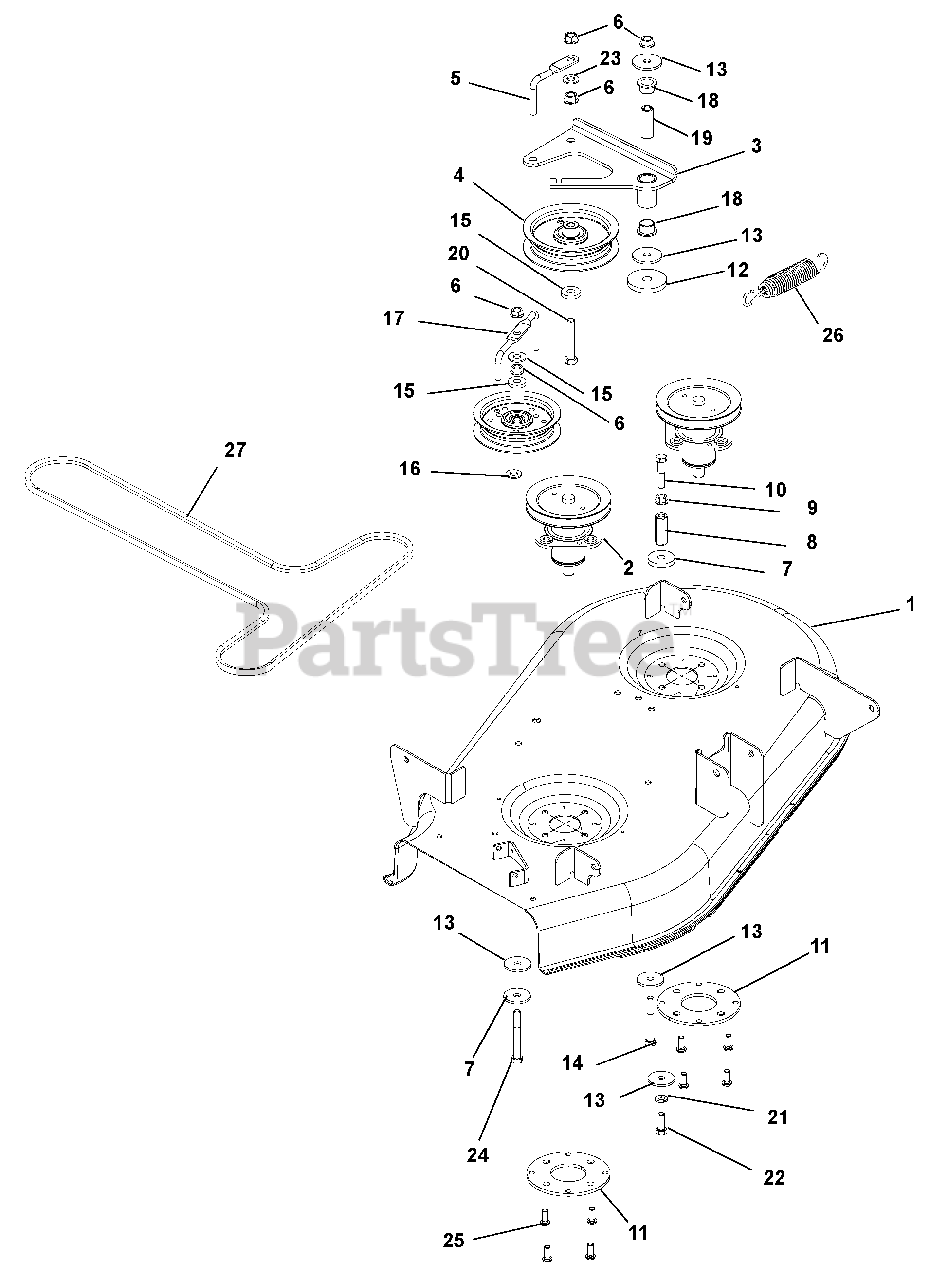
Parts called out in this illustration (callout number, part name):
1	Kit, Gravely 34" Deck with Decals
2	Assembly, Spindle
3	Weldment, Idler Arm
4	Assembly, Idler 4"
5	Wireform, Belt Finger
6	Nut, Locking Top Flange .38-16
7	Washer, Flat Steel .406 x 1.50 x .245
8	Nut, Coupling .375-16 x 1.75
9	Nut, Spin Lock, Flange .375-16
10	Bolt, Hex .38-16 x 1.75
11	Plate, REINF, Spindle
12	Washer, Flat Steel .469 x 2.00 x .25
13	Washer, Flat Steel .380 x 1.50 x .125
14	Bolt, Hex .38-16 x 3.00
15	Washer, Flat Steel .406 x 1.00 x .188
16	Washer, Flat Steel .438 x 1.00 x .083
17	Belt Finger
18	Bushing, Flange, .625 x .750 x .500 x 1.00
19	Spacer, .375ID x .625D x 1.66 Promaster
20	Bolt, Hex .38-16 x 2.25
21	Washer, Locking .38 x .094 Regular
22	Bolt, Hex .38-16 x 1.00
23	Washer, Flat Steel .406 x .812 x .065
24	Bolt, Hex .38-16 x 2.75
25	Screw, Tapping .38-16 x .75 Hex Washer Head Thread Rolling
26	Spring, Tension .135 x .98 x 6.0
27	V-Belt, HA-Wrapped Clutching
